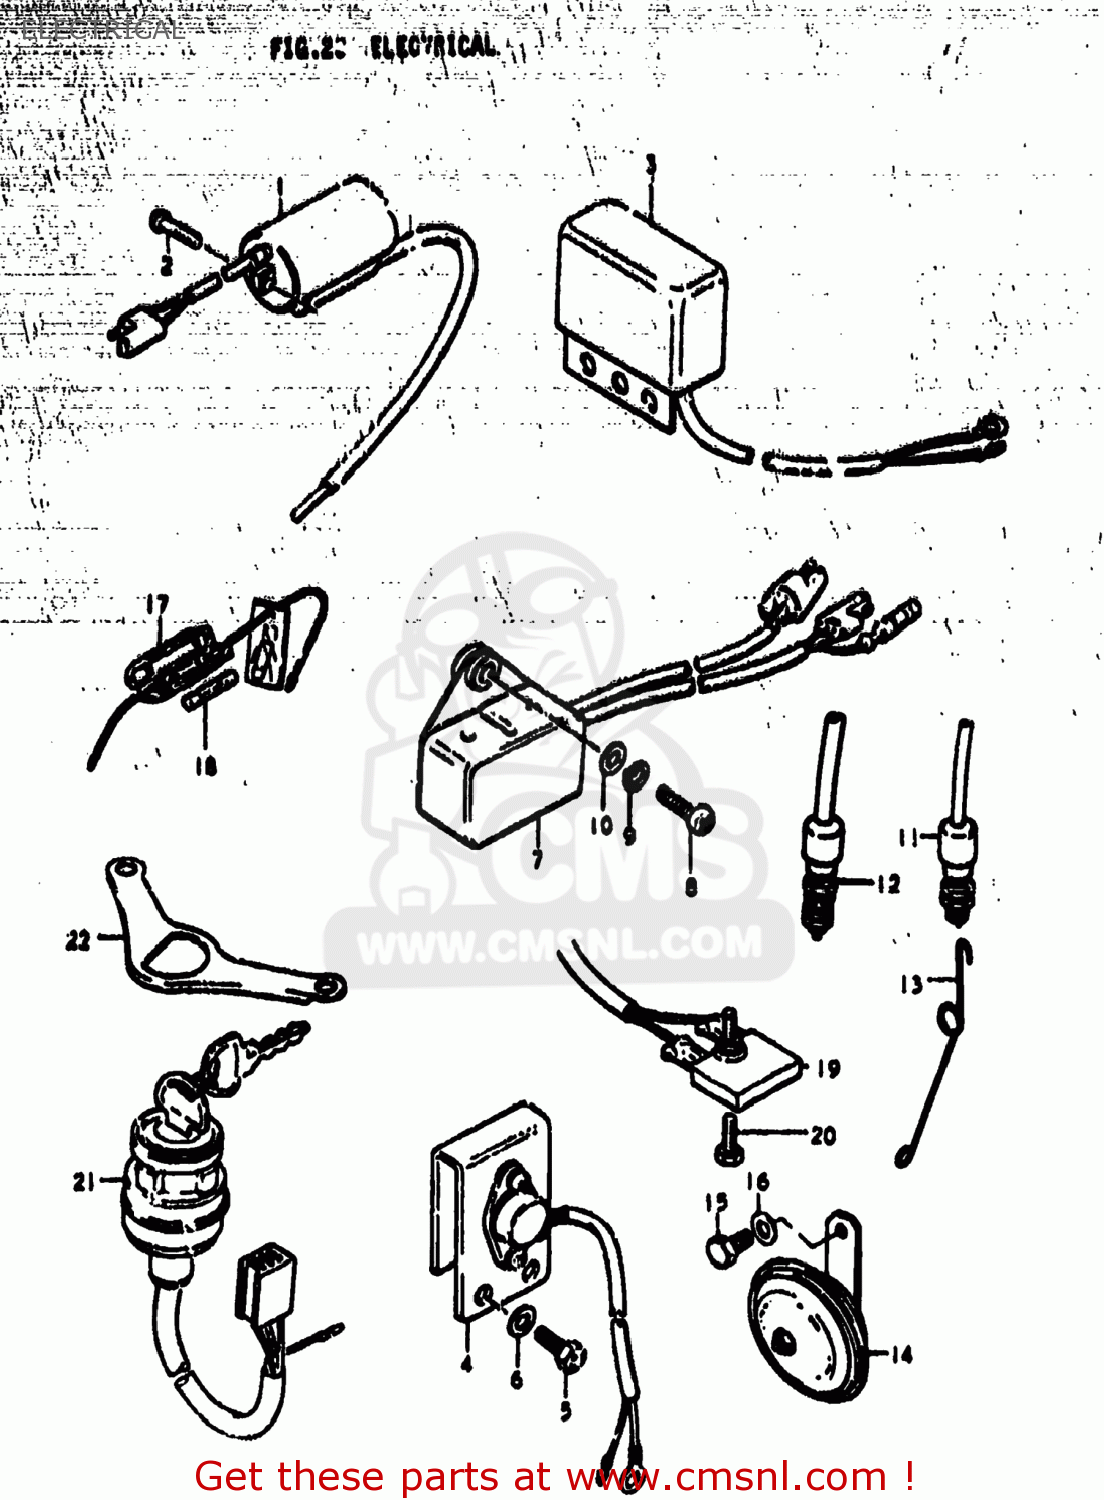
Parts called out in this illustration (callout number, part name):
1	COIL ASSY,IGNITION
2	SCREW 5X20
3	REGULATOR ASSEMBLY
4	REGULATOR ASSEMBLY
5	SCREW(5X12)
6	WASHER
7	CDI UNIT
8	SCREW
9	LOCK WASHER
10	WASHER
11	SWITCH ASSY, STOP LAMP
12	SWITCH ASSEMBLY,STOP LAMP
13	SPRING
14	HORN ASSEMBLY
15	BOLT
16	WASHER
17	BOX ASSEMBLY,FUSE
18	FUSE(15A)
19	RECTIFIER ASSEMBLY
20	SCREW
21	SWITCH ASSEMBLY,IGNITION
22	BRACKET,IGNITION SWITCH
